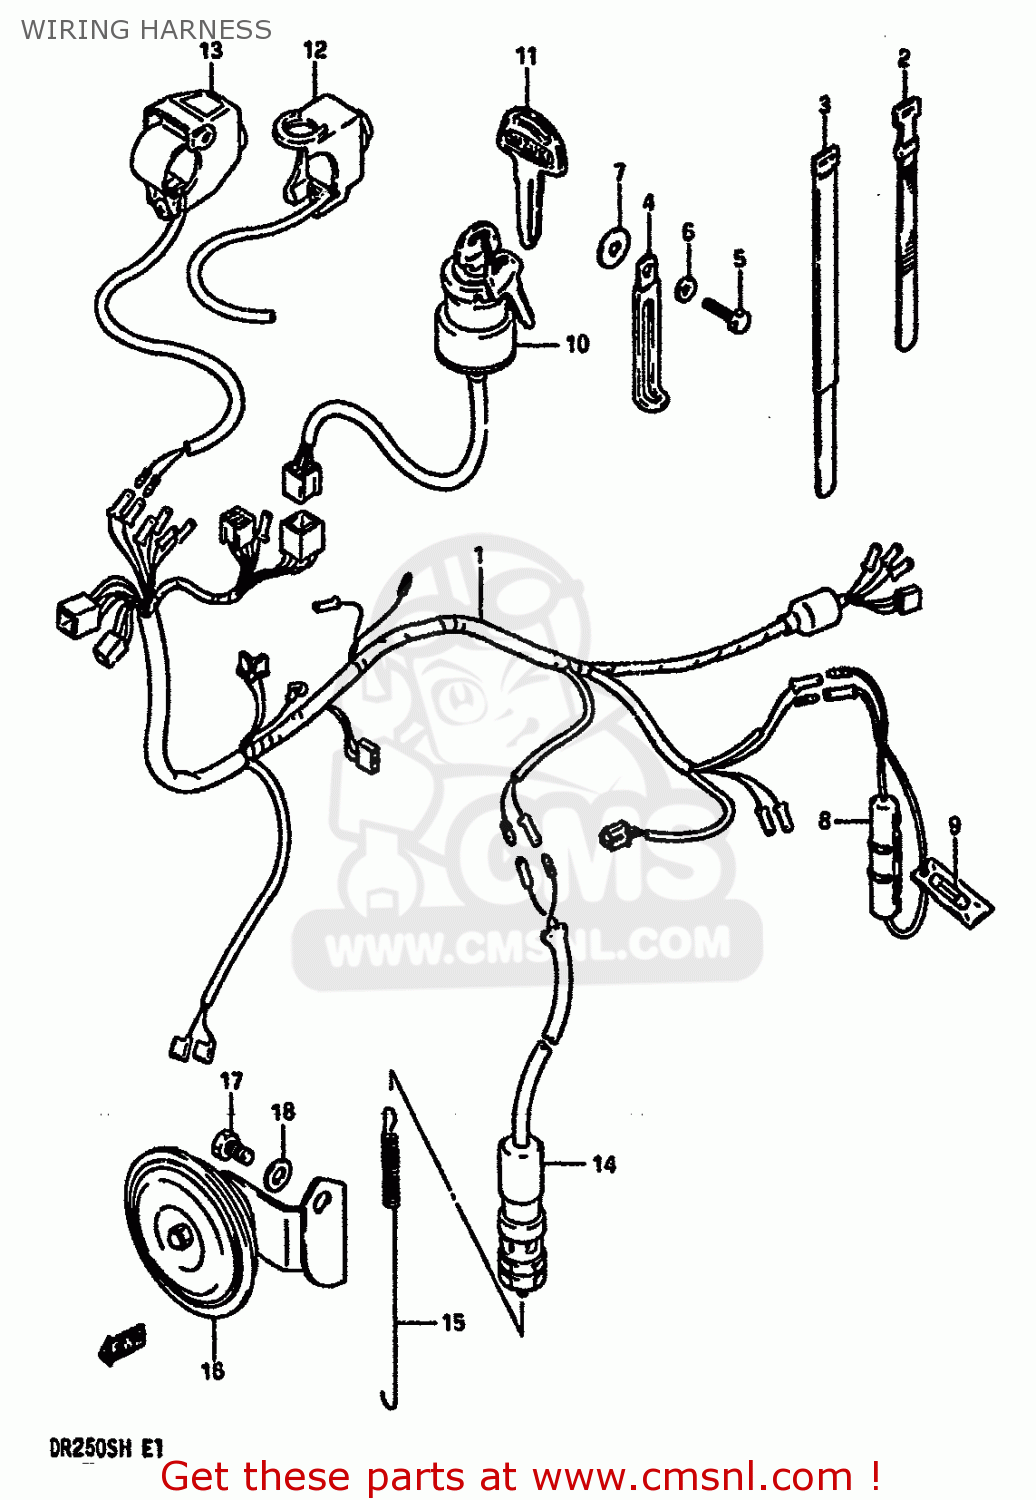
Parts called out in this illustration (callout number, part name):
1	HARNESS,WIRING
2	CLAMP(L:120)
3	CLAMP
4	CLAMP
5	BOLT 6X16
6	WASHER
7	WASHER
8	BOX ASSEMBLY,FUSE
9	FUSE(15A)
10	SWITCH ASSY,IGNITION
11	KEY,BLANK
12	SWITCH ASSY,ENGINE STOP
13	SWITCH ASSY,ENGINE STOP
14	SWITCH ASSY,STOP LAMP
15	SPRING
16	HORN ASSY
17	BOLT
18	WASHER
